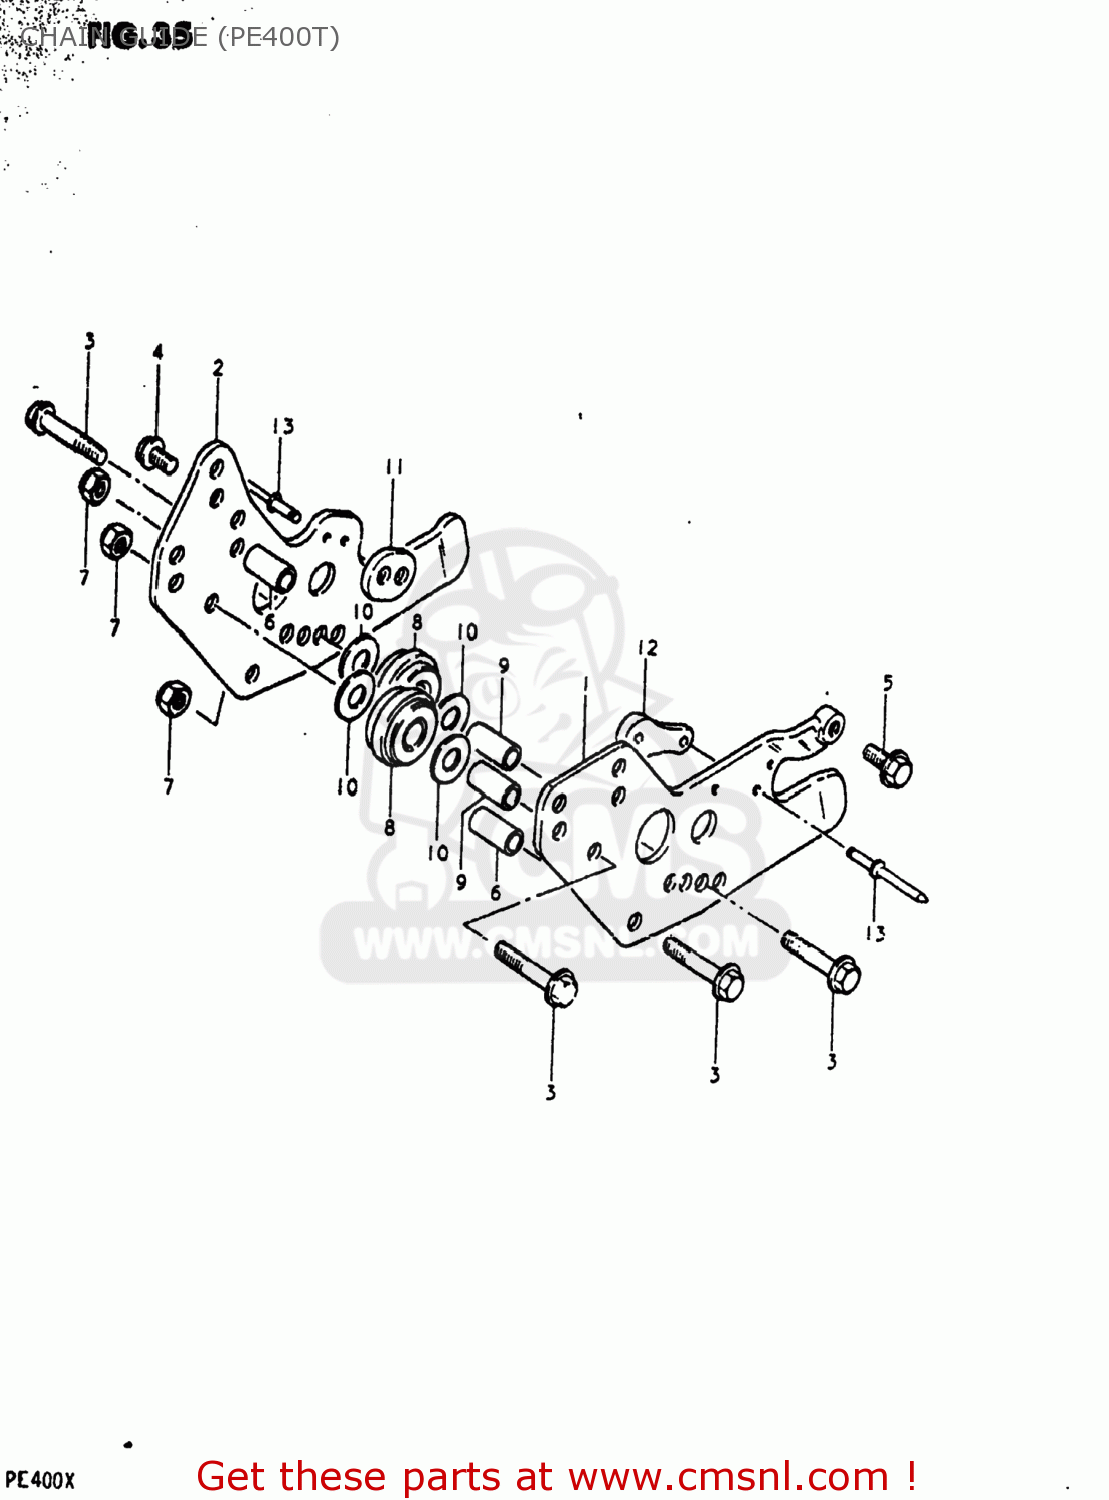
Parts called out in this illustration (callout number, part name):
1	PLATE,CHAIN GUIDE,OUTER
2	PLATE,GUIDE CHAIN
3	BOLT
4	BOLT
5	BOLT
6	SPACER(6.8X10X24.2)
7	NUT
8	ROLLER,CHAIN GUIDE
9	SPACER,CHAIN GUIDE ROLLER
10	WASHER
11	PAD,DRIVE CHAIN GUIDE
12	PAD,DRIVE CHAIN GUIDE
13	RIVET
